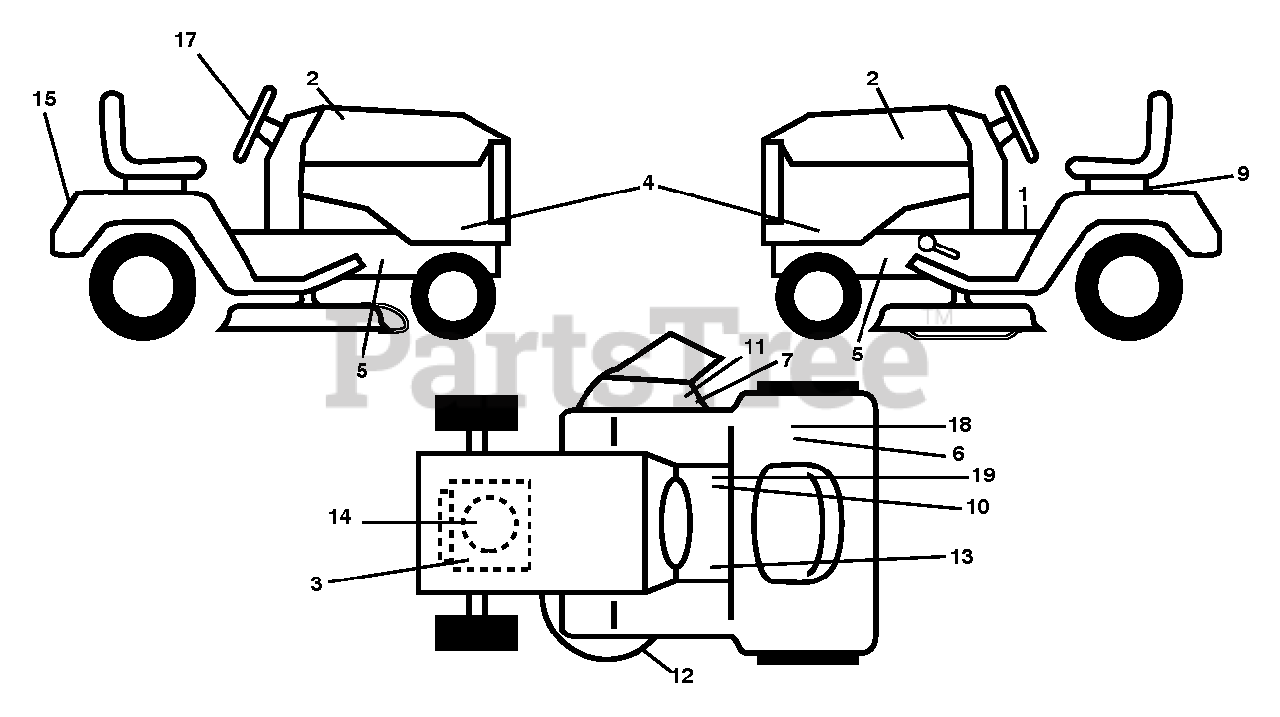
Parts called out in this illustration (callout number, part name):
6	DECAL.80 DBA.AUSTRALIA
7	DECAL, DEFLECT WARNING
9	DECAL BTRY SYMBOLS
10	DECAL PARK BRAKE
11	DECAL.INTERNATIONL.CUTFINGER
12	DECAL.V-BELT.SCHEMATIC.36/38/9
